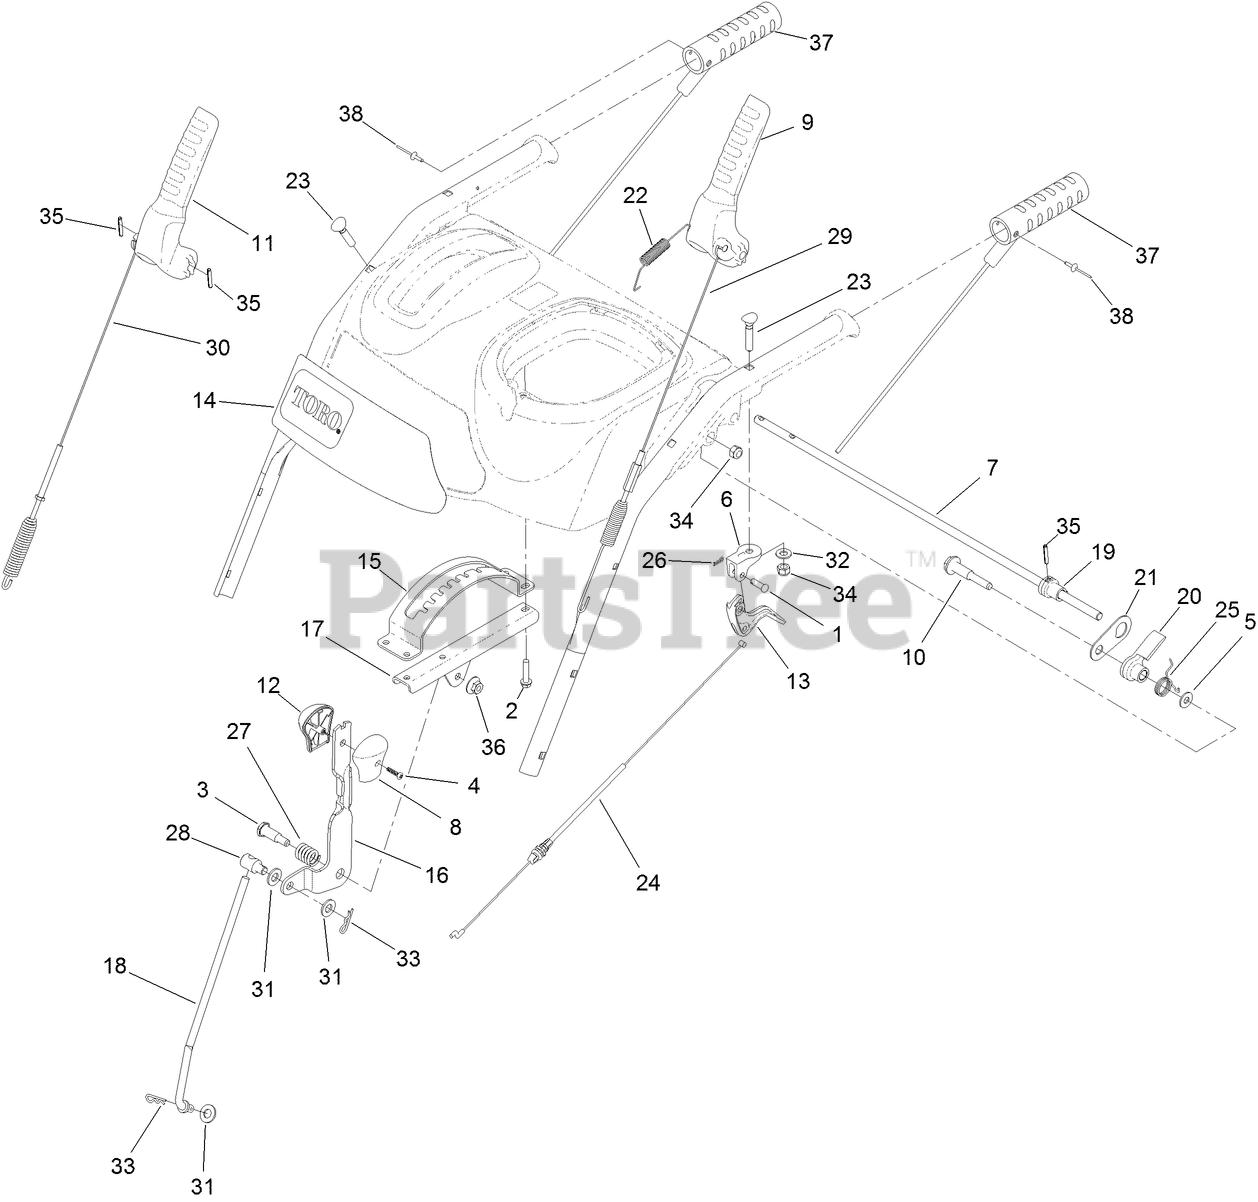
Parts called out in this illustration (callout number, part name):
1	PIN-CLEVIS
2	SCREW-PLASTITE
3	SCREW-SHOULDER
4	SCREW-PPH
5	WASHER-FLAT
6	MOUNT-CLUTCH, LEVER
7	ROD-LOCKOUT
8	KNOB-SHIFT, LH
9	LEVER-TRACTION
10	SCREW-SHOULDER
11	LEVER-AUGER
12	KNOB-SHIFT, RH
13	LEVER-CLUTCH
14	DECAL-CONTROL PANEL
15	GUIDE-SELECTOR, SPEED
16	SELECTOR-SPEED
17	BRACKET-SELECTOR, SPEED
18	ROD-SHIFT
19	CAM-LOCKOUT
20	LATCH-LOCKOUT
21	LINK-LOCKOUT
22	SPRING-TENSION
23	SCREW-HANDLE
24	CABLE-CLUTCH
25	SPRING-TORSION
26	PIN-HAIR
27	SPRING-COMPRESSION
28	TRUNNION-ROD
29	CABLE-TRACTION
30	CABLE-AUGER
31	WASHER-FLAT
32	WASHER-FLAT
33	PIN-COTTER
34	NUT-LOCK, NI
35	PIN-SPRING
36	NUT-HF
37	GRIP-HEATED
38	RIVET-POP
